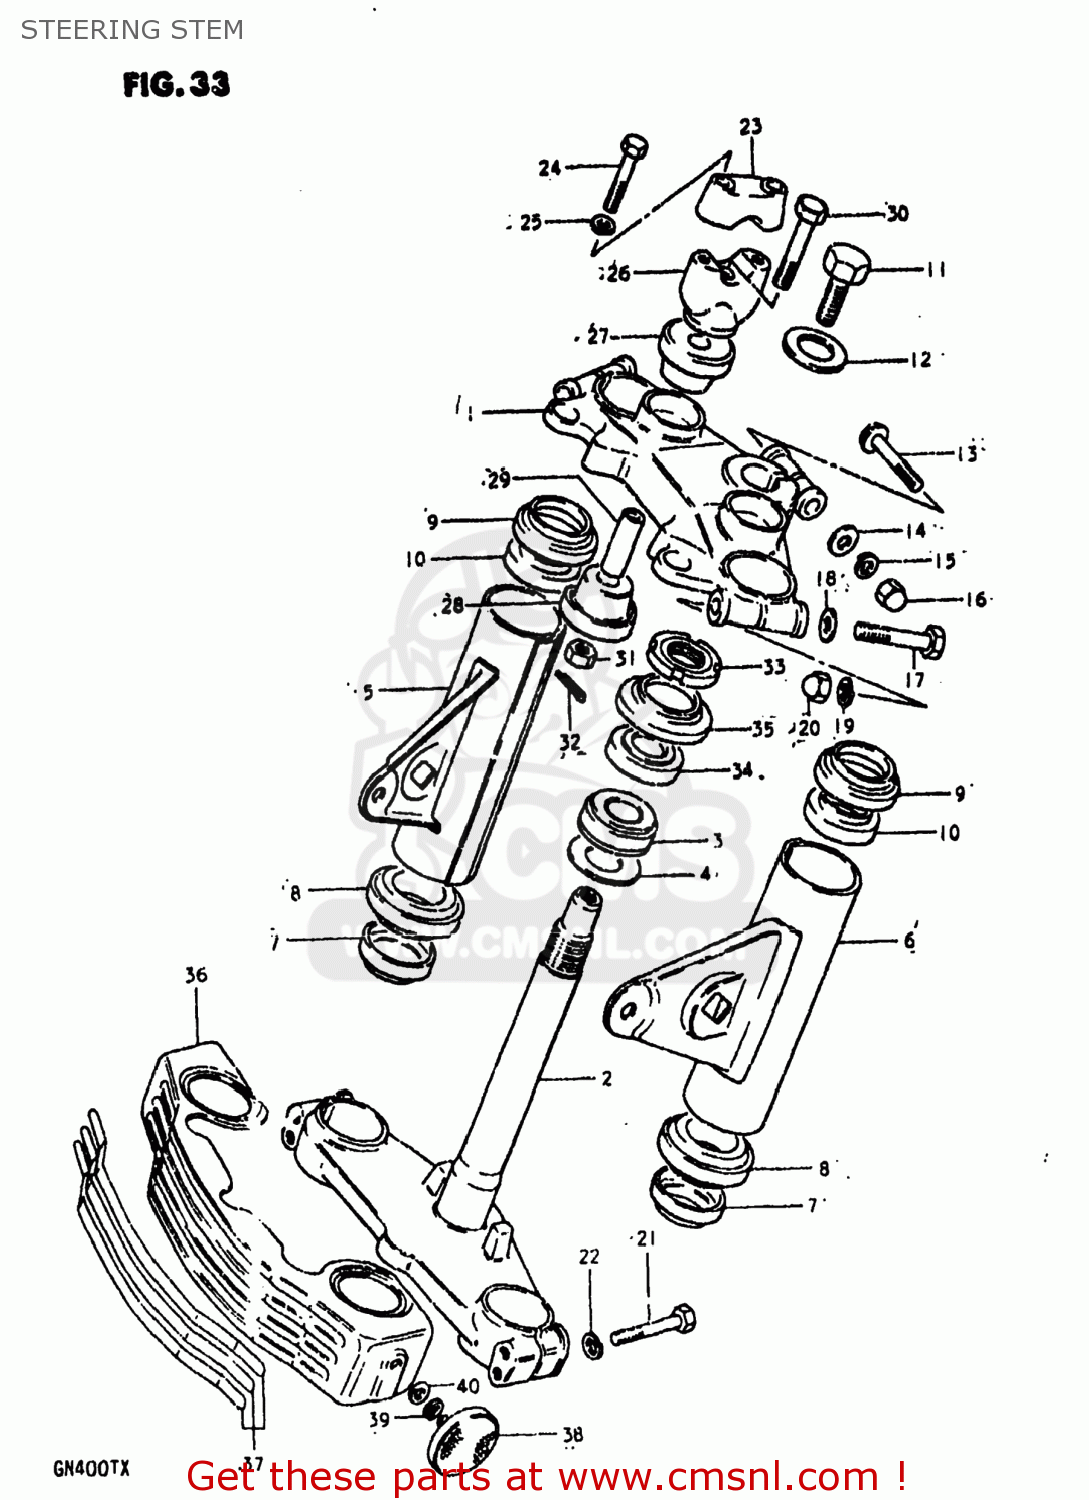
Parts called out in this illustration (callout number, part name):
1	HEAD,STEERING STEM
2	STEM,STEERING
3	BEARING
4	WASHER,THRUST
5	BRACKET,HEADLAMP,RIGHT
6	BRACKET,HEADLAMP,LEFT
8	CUSHION,HEADLAMP BRACKET
9	CAP,HEAD LAMP B
10	CUSHION,HEADLAMP BRACKET
11	BOLT(12X20)
12	WASHER
13	BOLT
14	WASHER
15	LOCK WASHER
16	NUT,M8X1.25X12
17	BOLT 10X55
18	WASHER
19	LOCK WASHER
20	NUT 10MM
21	BOLT 8X45
22	WASHER,LOCK,8.
23	HOLDER,HANDLE UPR
24	BOLT
25	LOCK WASHER
26	CLAMP,HANDLEBAR,LOWER
27	CUSHION,UPR
28	CUSHION
29	SPACER(10.2X14X46)
30	BOLT(10X78)
31	NUT
32	COTTER PIN
33	NUT,STEERING STEM(25X44X10)
34	TAPER,ROLLER BEARING
35	DUST SEAL,STEERING,UPPER
36	COVER,FRONT FORK
37	TAPE SET,FRONT FORK COVER
38	REFLEX REFLECTOR,FR
39	LOCK WASHER
40	WASHER
